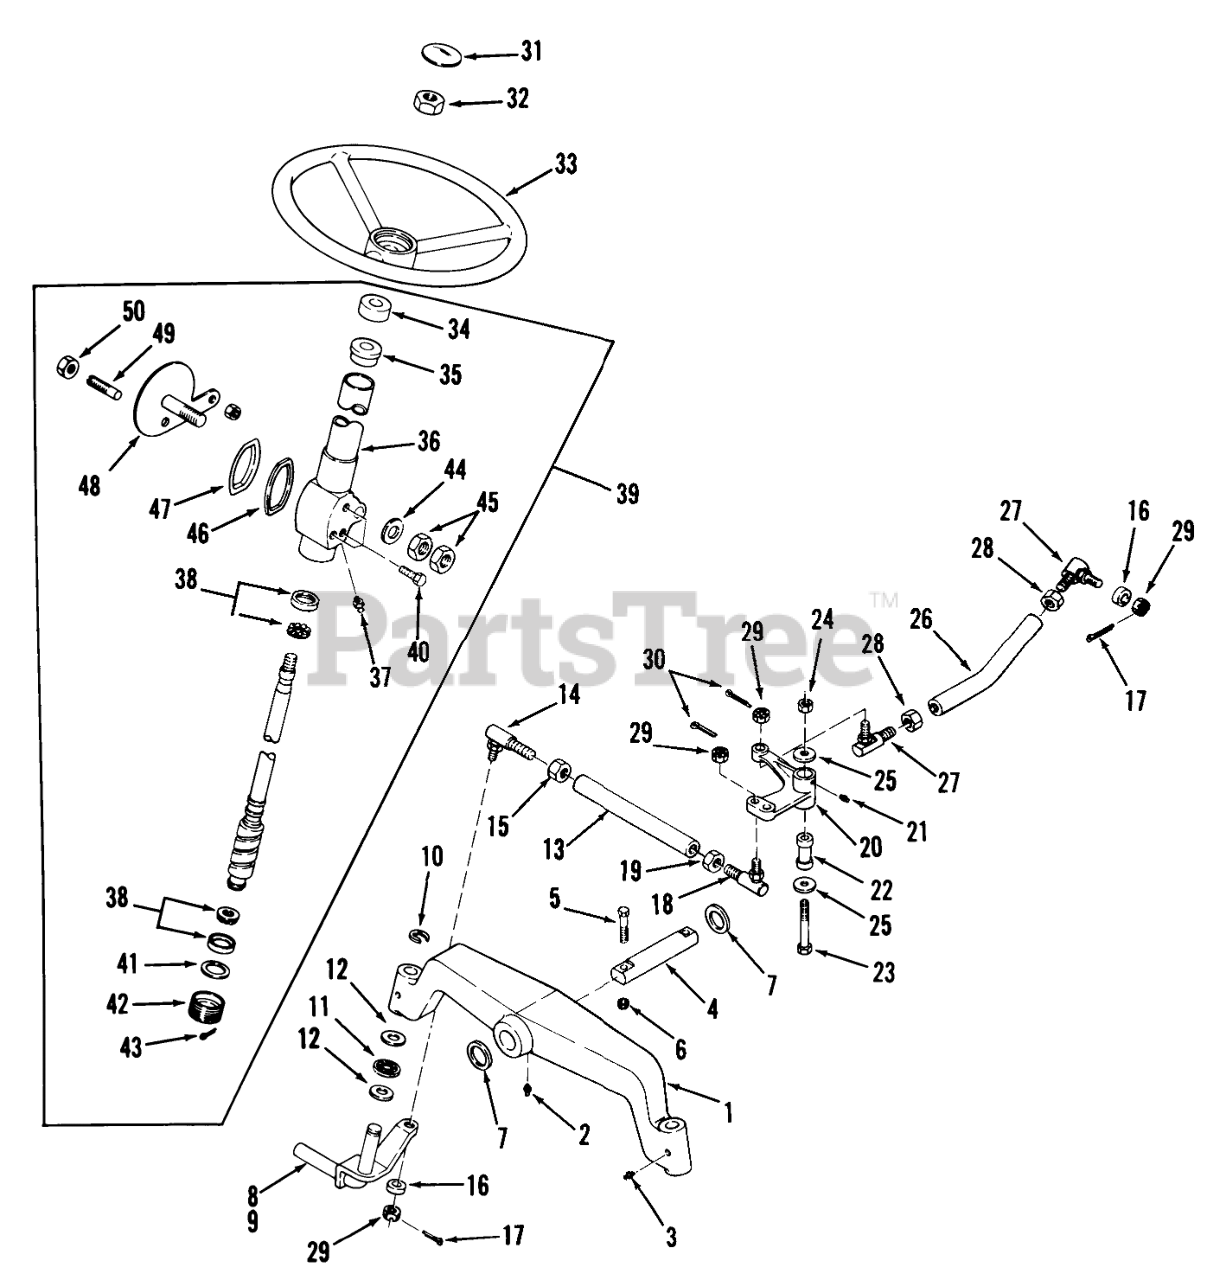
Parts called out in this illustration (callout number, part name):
1	Axle Front
2	FITTING-GREASE
3	Zerk
4	PIN AXLE
6	Nut
7	Washer
8	Spindle Assembly R.H.
9	ASSY-SPNDLE&STEER R
10	E RING
11	BEARING-THRUST
12	WASHER-THRUST
13	TIE ROD R
14	Ball Joint RH
15	NUT-6
16	Washer
17	Cotter Pin
18	LH BALL JOINT R
19	Jam Nut LH 1/2-20
20	Bellcrank-steering
21	Zerk
22	Bushing
23	HEX HD CAP SCREW
24	Nut
25	Washer
26	Drag Link
27	BALL JOINT-SHORT R
28	NUT-6
29	Slot Nut 3/8-24
30	Cotter Pin
31	STEERING WHEEL INSE
32	Nut
33	Steering Wheel
34	Cover-Dust
35	Column Bearing
36	Assy-Housing and Column
37	Fitting-Grease
38	BALL CUP KIT
39	Steering Gear
40	BOLT
41	WASHER
42	Adjusting Plug
43	Cotter Pin
44	Washer 49/64 X 1 1/4
45	Nut
47	Retainer-Seal
48	Lever
49	Stud
50	Nut
